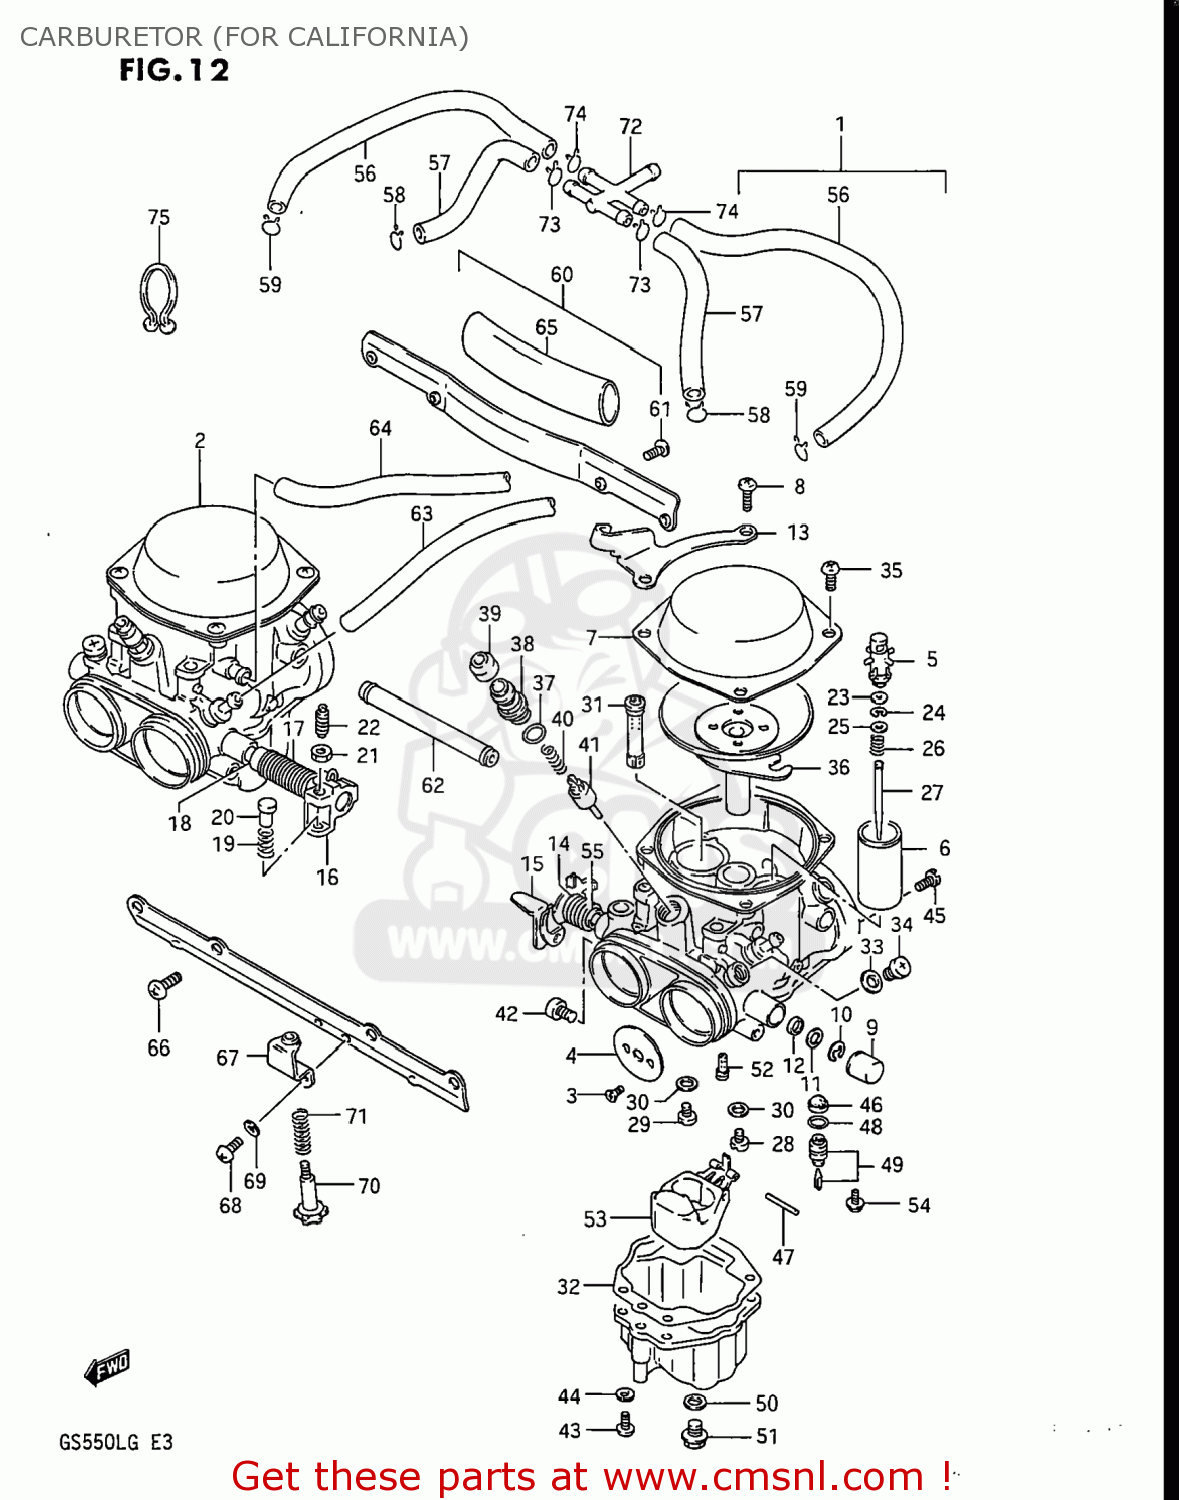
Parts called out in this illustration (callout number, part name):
1	CARBURETOR ASSEMBLY
2	CARBURETOR ASSEMBLY
3	SCREW
4	VALVE,THROTTLE
5	HOLDER,GUIDE
6	VALVE,THROTTLE
7	COVER,DIAPHRAGM
8	SCREW
9	CAP,THROTTLE SHAFT
10	E RING
11	GASKET,THROTTLE SHAFT (NAS)
12	SEAL
13	BRACKET,THROTTLE CABLE
14	SPRING,THROTTLE SHAFT
15	SHAFT ASSEMBLY
16	SHAFT ASSEMBLY
17	SPRING
18	RING
19	SPRING,THROTTLE SCREW
20	PIN,THROTTLE LEVER
21	NUT
22	SCREW
23	RING
24	CAP,LEVER
25	WASHER
26	SPRING
27	NEEDLE JET
28	JET,MAIN(90)
29	JET,MAIN(97.5)
30	WASHER,NEEDLE NOZZLE
31	JET,NEEDLE
32	GASKET,FLOAT CHAMBER (MCA)
33	WASHER
34	SCREW
35	SCREW
36	DIAPHRAGM,CARBURETOR
37	O RING
38	HOLDER,GUIDE
39	CAP
40	SPRING
41	VALVE,STARTER
42	SCREW
43	SCREW
44	LOCK WASHER
45	JET,PILOT(150)
46	FILTER
47	PIN,FLOAT
48	O-RING,NEEDLE VALVE
49	VALVE ASSEMBLY,NEEDLE
50	GASKET (NAS)
51	PLUG,DRAIN
52	JET,PILOT(37.5)
53	FLOAT
54	SCREW
55	RING,THROTTLE SHAFT
56	HOSE
57	HOSE
58	CLIP
59	CLIP
60	FLANGE ASSEMBLY,CARBURETOR
61	SCREW
62	PIPE,CARBURETOR
63	HOSE 4.5X8X390
64	HOSE
65	HOSE(16X19X100)
66	SCREW
67	BRACKET,SLOW ADJUST
68	SCREW
69	WASHER,LOCK
70	ADJUSTER
71	SPRING
72	SPRING
73	CLIP
74	CLIP
75	CLIP(ID:16)
